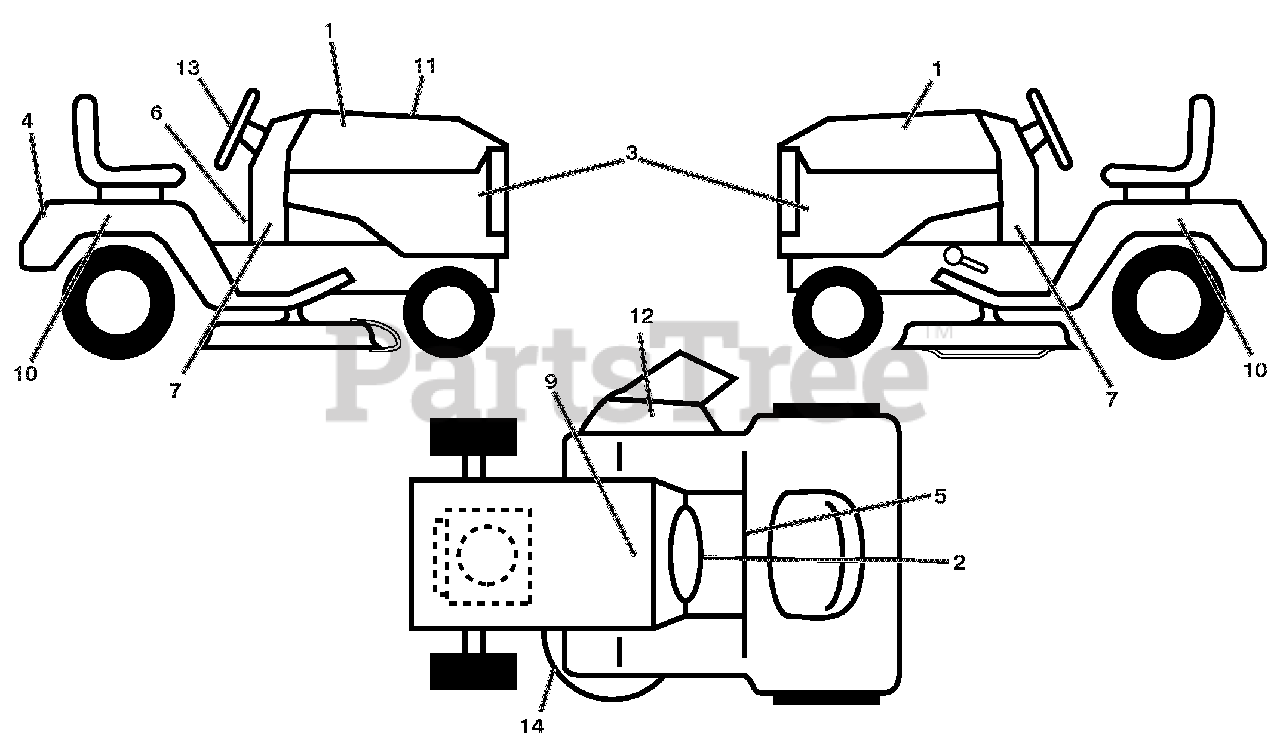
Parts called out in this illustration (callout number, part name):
1	DECAL.HOOD.LH/RH.
2	DECAL.WARNING.START
3	DECAL.SDPNL.PWRDBY KOHL.ARIENS
4	DECAL.FENDER.REAR.ARIENS
5	DECAL.FENDER
6	Decal, Spark Arrester
7	DECAL DASH LOWER
9	DECAL.BAT.DAN/POI P/L SYM.WPN
10	DECAL, FENDER
11	DECAL, REPLACEMENT
12	DECAL DECK/DEFLECT. WARNING
13	DECAL.WHEEL.STEER.ARIENS
14	DECAL.V-BELT.SCH.
